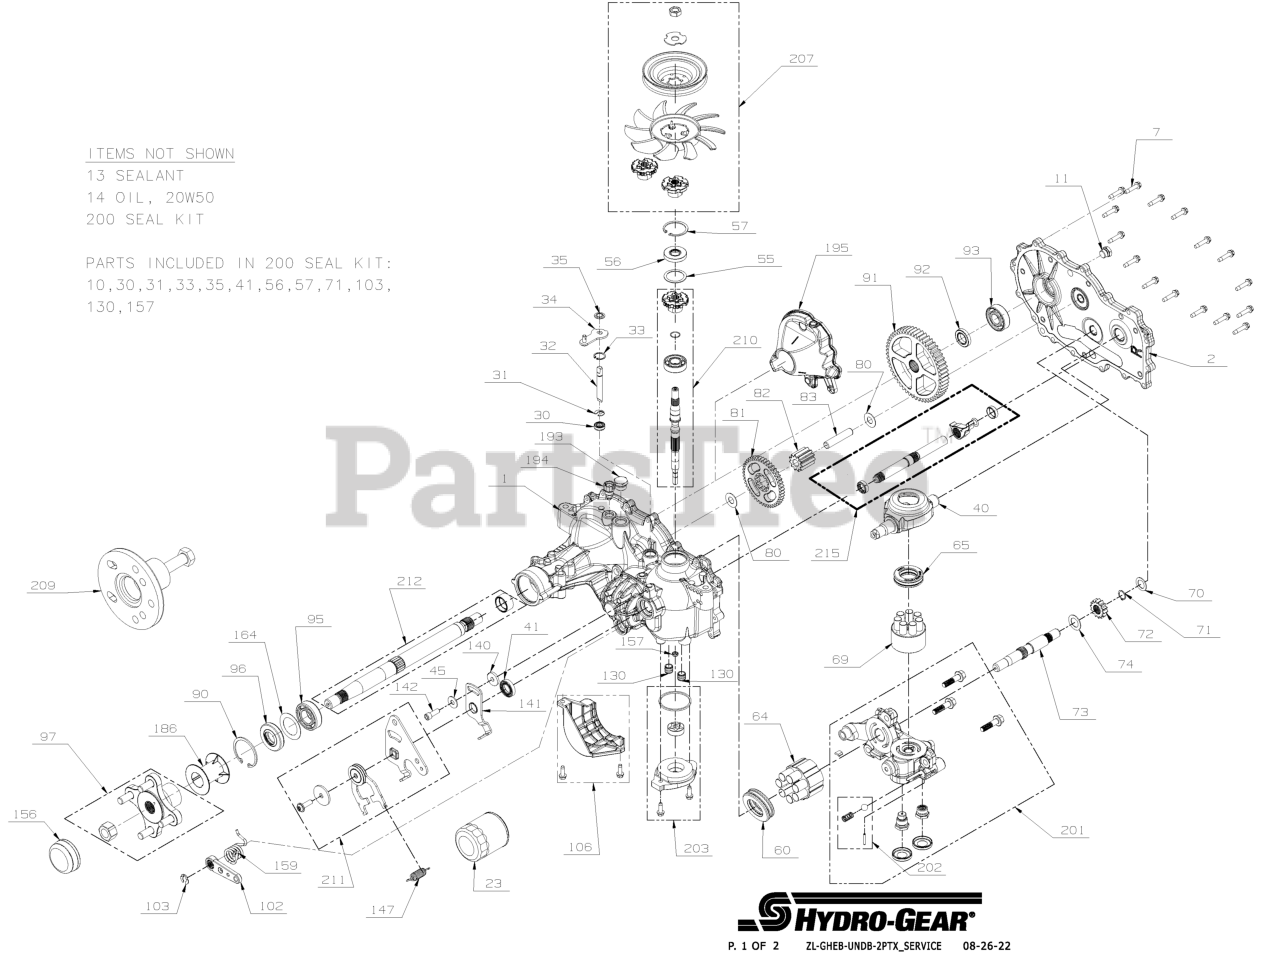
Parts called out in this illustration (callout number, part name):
1	KIT, HOUSING, MAIN, RH, CHRG, CNTL
2	KIT, SIDE COVER, RH
7	SCREW,HEX WASHER 1/4-20X1.125
11	PLUG EXT HEX VENT 9/16 18
13	SEALANT TUBE 10.1OZ.
14	FLUID, HYDRO 15W50 QT
14	FLUID, HYDRO 20W50 QT
23	FILTER, HYDRO-GEAR 2800 TRANS
30	Seal, lip .375 x 375 x 325
31	RING. RETAINING
32	ROD, BYPASS
33	RING, RET .750
34	ARM, BYPASS
35	SHCS 5/16-24X1 PATCH
40	TRUNNION, SWASHPLATE
41	SEAL, LIP 18X32X7
55	WASHER 1.23X1.56X.04
56	SEAL, LIP 17 X 40 X 7 HNBR
57	RING, RET 1.56 INT
60	HG THRUST BEARING (51462)
64	HG 16CC CYLINDER BLOCK (71579)
65	BEARING. THRUST 30 X 52 X 13
69	ASSY, BLOCK 7 PISTON
70	WASHER .63X1.0X.05
71	RING, RET 62 EXT
72	GEAR 14T STEEL
73	SHAFT, MOTOR
74	WASHER .71 X 1.16 X .04
80	WASHER .5X1.0X.032
81	GEAR 45 TOOTH
82	GEAR 11 TOOTH STEEL
83	JACK SHAFT (PIN)
90	RING, RETAINING
91	GEAR 54 TOOTH
92	SPACER
93	KIT, BEARING
95	BEARING, BALL 25.4 X 52 X 15
96	SEAL, LIP
97	KIT, HUB 4 BOLT
102	HANDLE- ACTUATING
103	CLIP,BRAKE ARM HYDROGEAR 52027
106	KIT FILTER GUARD
130	TUBE CHARGE TRIPLE ORING
141	ARM, NEUTRAL RIGHT
142	SHCS 5/16-24X1 PATCH
156	CAP, AXLE
157	KIT GEROTOR SEAL
159	SPRING, TORSION, CW
164	WASHER, 1.355 x 2.035 x .021 FLAT
186	TUBE, AXLE 2.03
194	ASSEMBLY, FITTING 9/16-18 BREATHER
195	ASSEMBLY, TANK, EXPANSION, INTERNAL, RH
200	KIT, SEAL
201	KIT, CENTER SECTION RH, CHARGE
202	KIT CHARGE RELIEF
203	KIT, CHARGE
207	KIT- FAN/PULLEY
209	HUB PULLER 5 BLT
210	KIT INPUT SHAFT
211	KIT RTN BIDIRECTIONAL
212	KIT, SHAFT, AXLE
215	KIT, OUTBOARD, RH ROT B / LH ROT A
